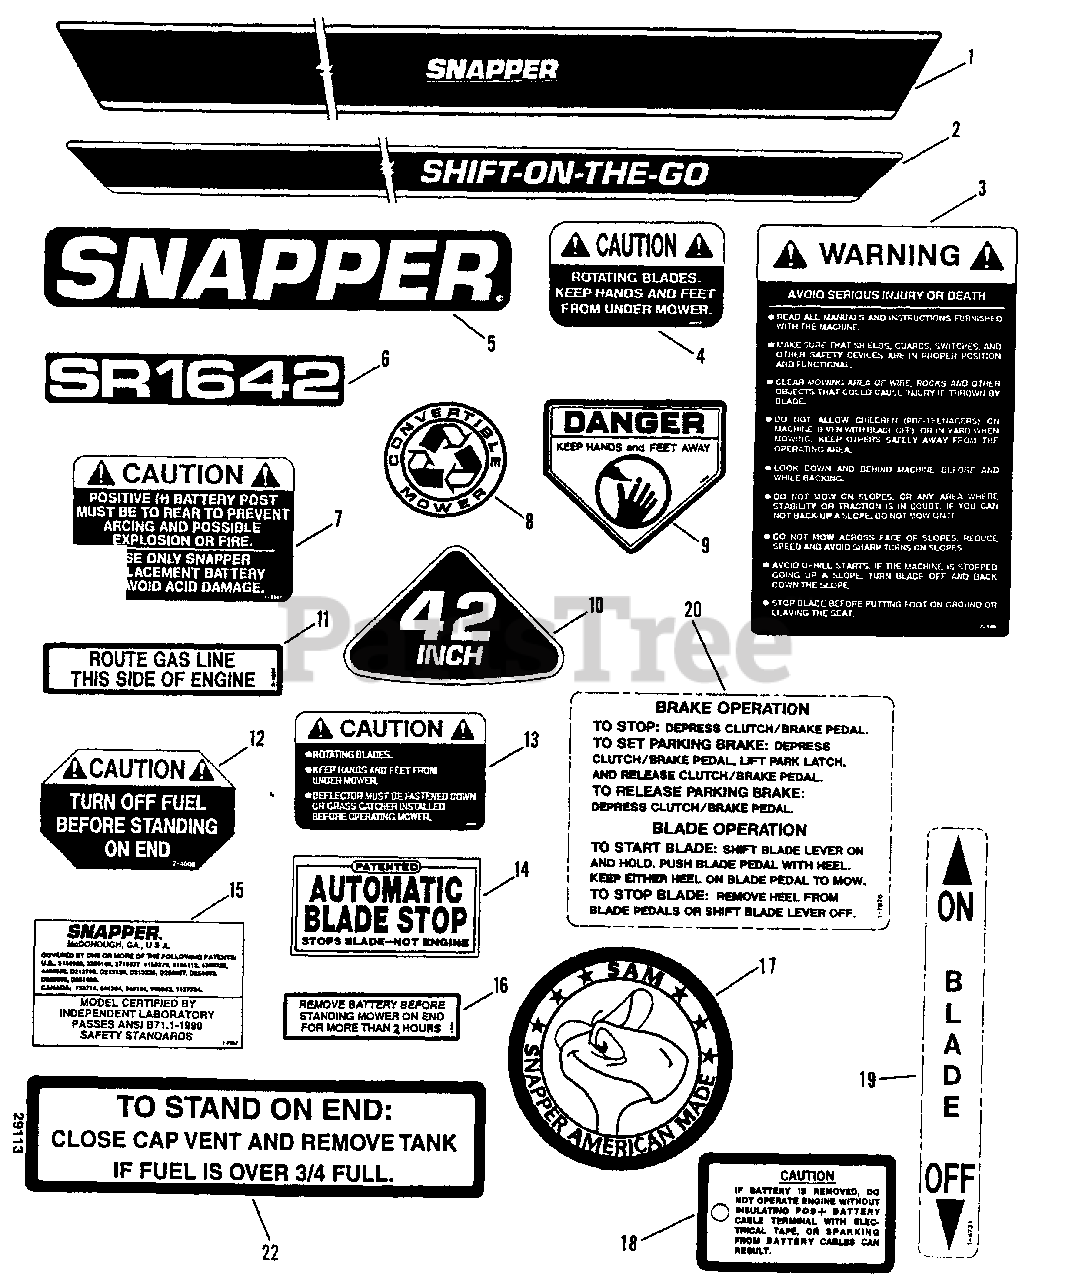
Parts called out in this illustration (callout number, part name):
1	DECAL, Banner (Blue)
2	DECAL, Bumper Stripe (Blue)
3	DECAL, Warning, Safety Instruction
4	DECAL, Caution, Rotating Blades
5	SNAPPER (Molded Logo)
6	DECAL, SR1642
7	DECAL, Caution, Battery
8	LOGO, Convertible (Blue)
9	DECAL, Danger
10	DECAL, 42 Inch
11	DECAL, Fuel Routing
12	DECAL, Fuel Shut-Off
13	DECAL, Caution
14	DECAL, Automatic Blade Stop
15	DECAL, Patent
16	DECAL, Battery Storage
17	MEDALLION, SAM
18	DECAL, Caution
19	DECAL, Blade Engagement
20	DECAL, Brake Operation
22	DECAL, Caution Fuel
